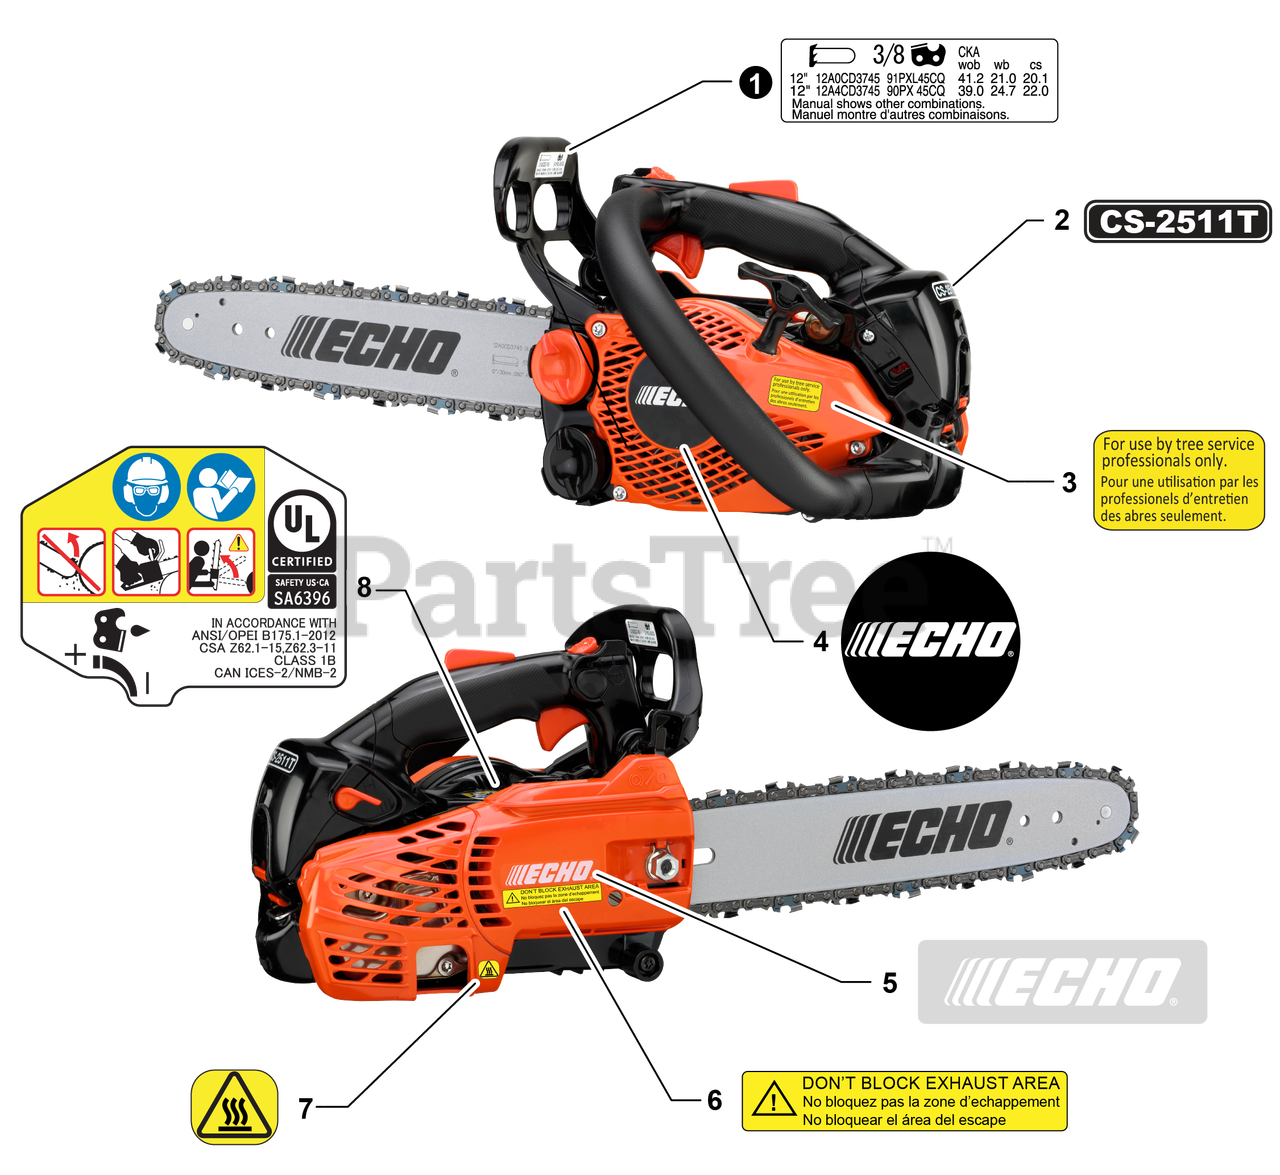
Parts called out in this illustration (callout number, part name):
1	LABEL, BAR & CHAIN
2	LABEL, CS-2511T
3	LABEL, CAUTION - PROFESSIONALS ONLY
4	LABEL, ECHO
5	LABEL, ECHO
6	LABEL, CAUTION - DON'T BLOCK EXHAUST AREA
7	LABEL, CAUTION - HOT
8	LABEL, CAUTION
